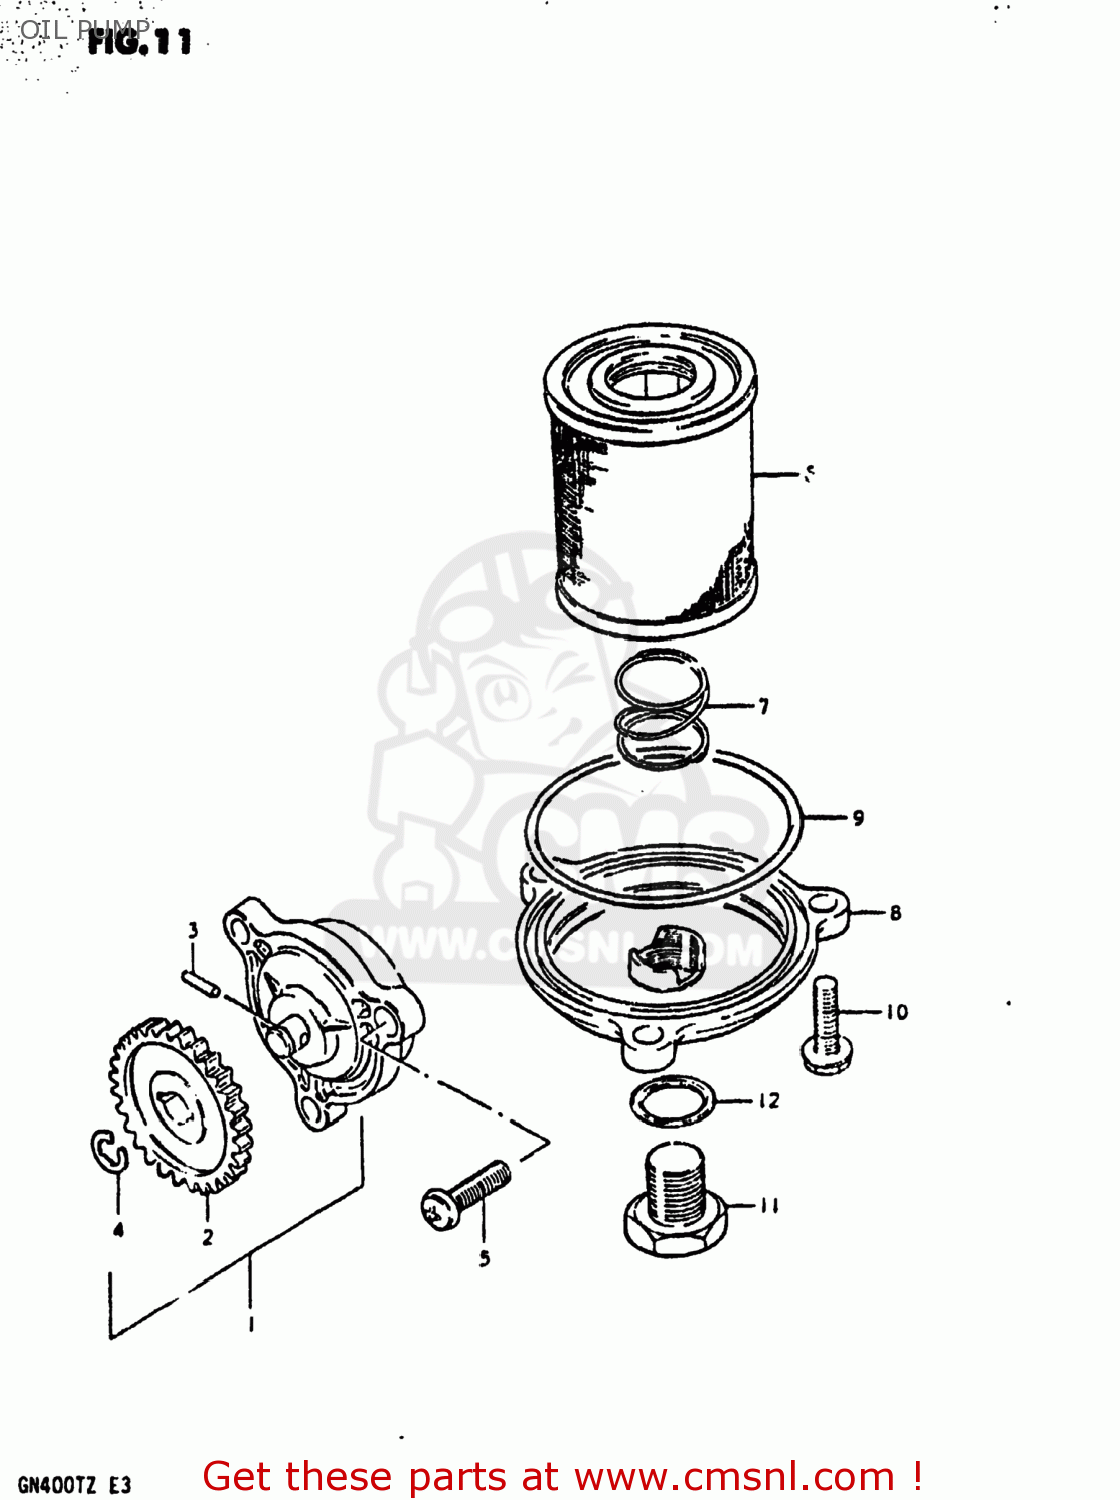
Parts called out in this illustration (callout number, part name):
1	PUMP ASSEMBLY,ENGINE OIL
2	GEAR,OIL PUMP DRIVEN
3	PIN(2.5X11.8)
4	E RING 6MM
5	SCREW
6	STRAINER,OIL
7	SPRING
8	CAP,ENGINE OIL STRAINER
9	O RING(D:2.4,ID:62.6)
10	BOLT,REAR
11	PLUG
12	GASKET(14X19.2X2) (NAS)
